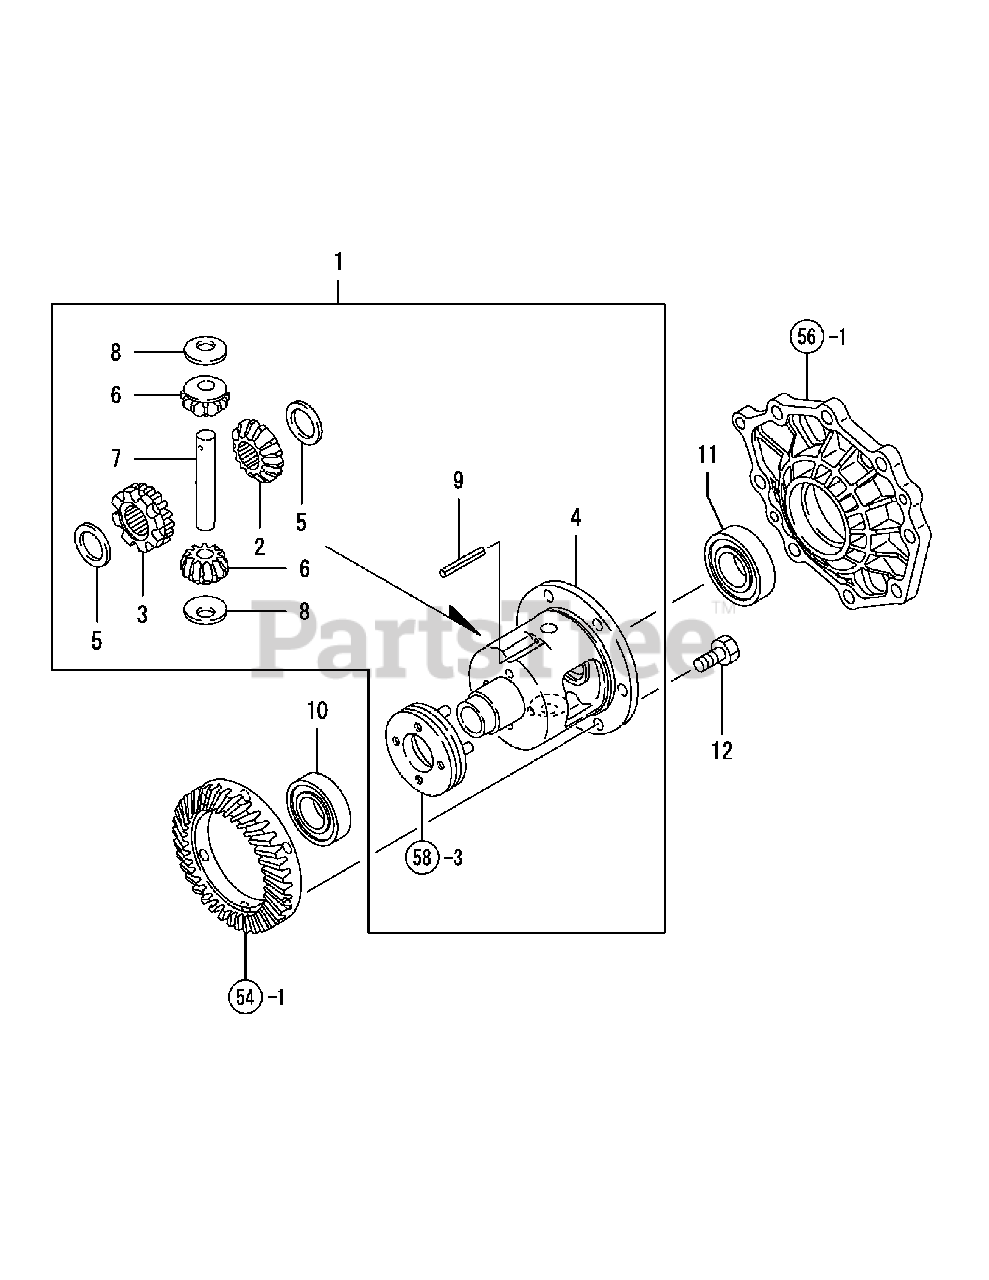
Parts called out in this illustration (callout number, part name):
1	Case Assy,Diff
2	Gear, Diff.Side
3	Gear, Diff.Side (Lock
4	Case, Differential
5	Liner, Diff.Side Gear
6	Gear, Differential
7	Shaft, Differential
8	Washer, Differential
9	Spring Pin 4X40
